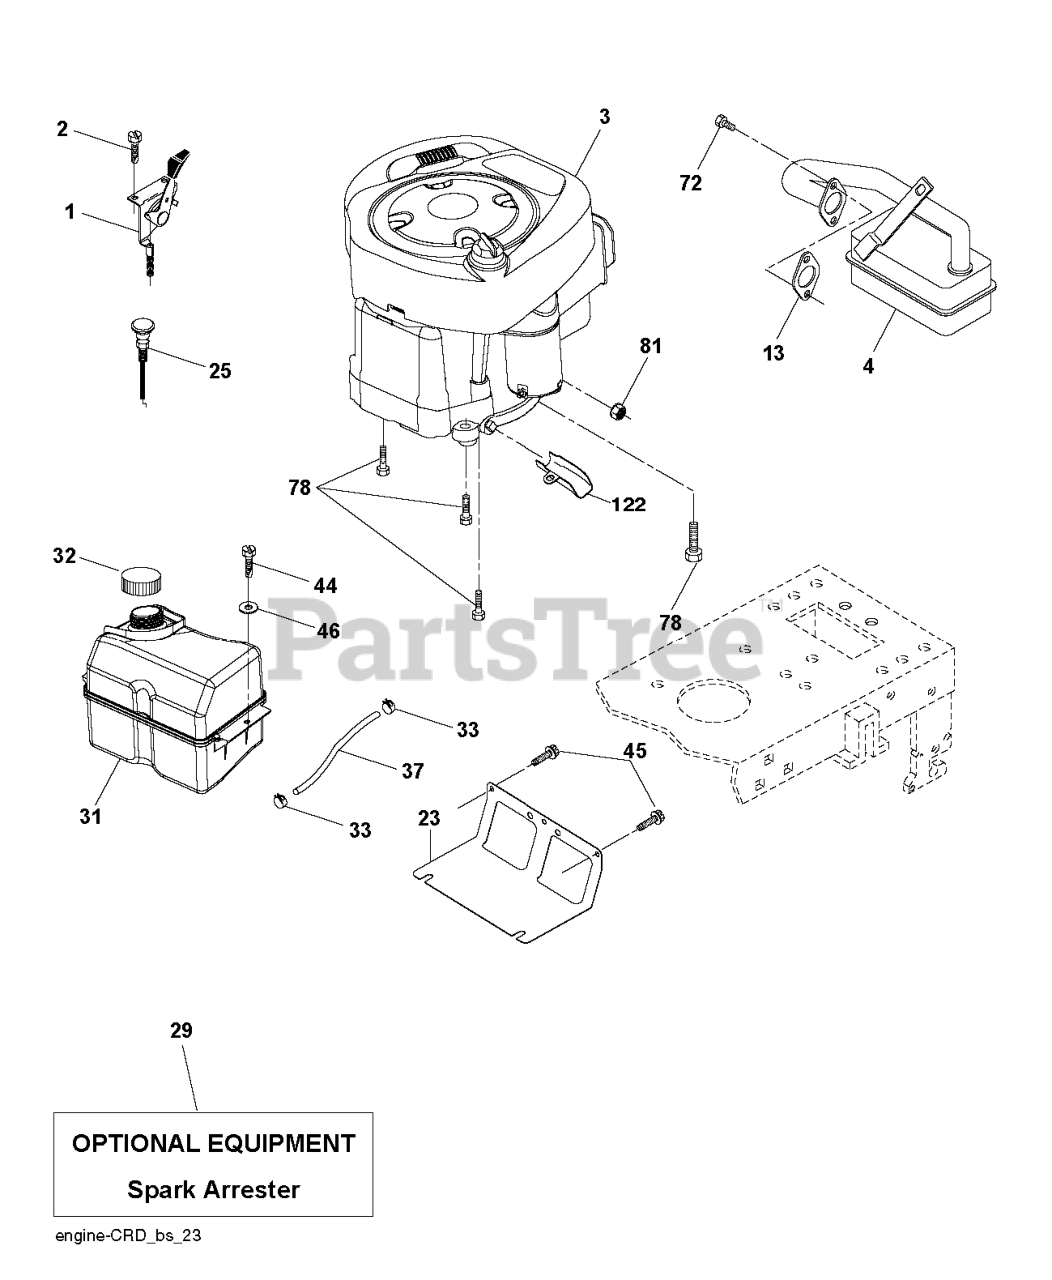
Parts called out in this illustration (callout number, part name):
1	CONTROL.THROTTLE/CHOKE.BLACK
2	SCREW
4	MUFFLER.B&S.MODEL.21.11HP.OHV
13	REPL BY 532 27 22-93
23	SHIELD.BROWNING.DBR.GUARD
25	KNOB.ERGO.EXTENDED.RED (1 2)
29	KIT.SPARK ARRESTOR 794945 B&S
31	TANK.FUEL.FRT.N/CAP.2.0GAL.DAP
32	CAP ASM.FUEL.2.25"FR.
33	HOSE CLAMP
37	LINE.FUEL.20
44	SCREW HEXWSHR 1/4-20X3/4
45	SCREW, 3/8-16X3/4
72	SCREW.SOCKET HD.5/16-1
78	SCREW.3/8-16
81	NUT
122	EXTENSION DRAIN OIL
